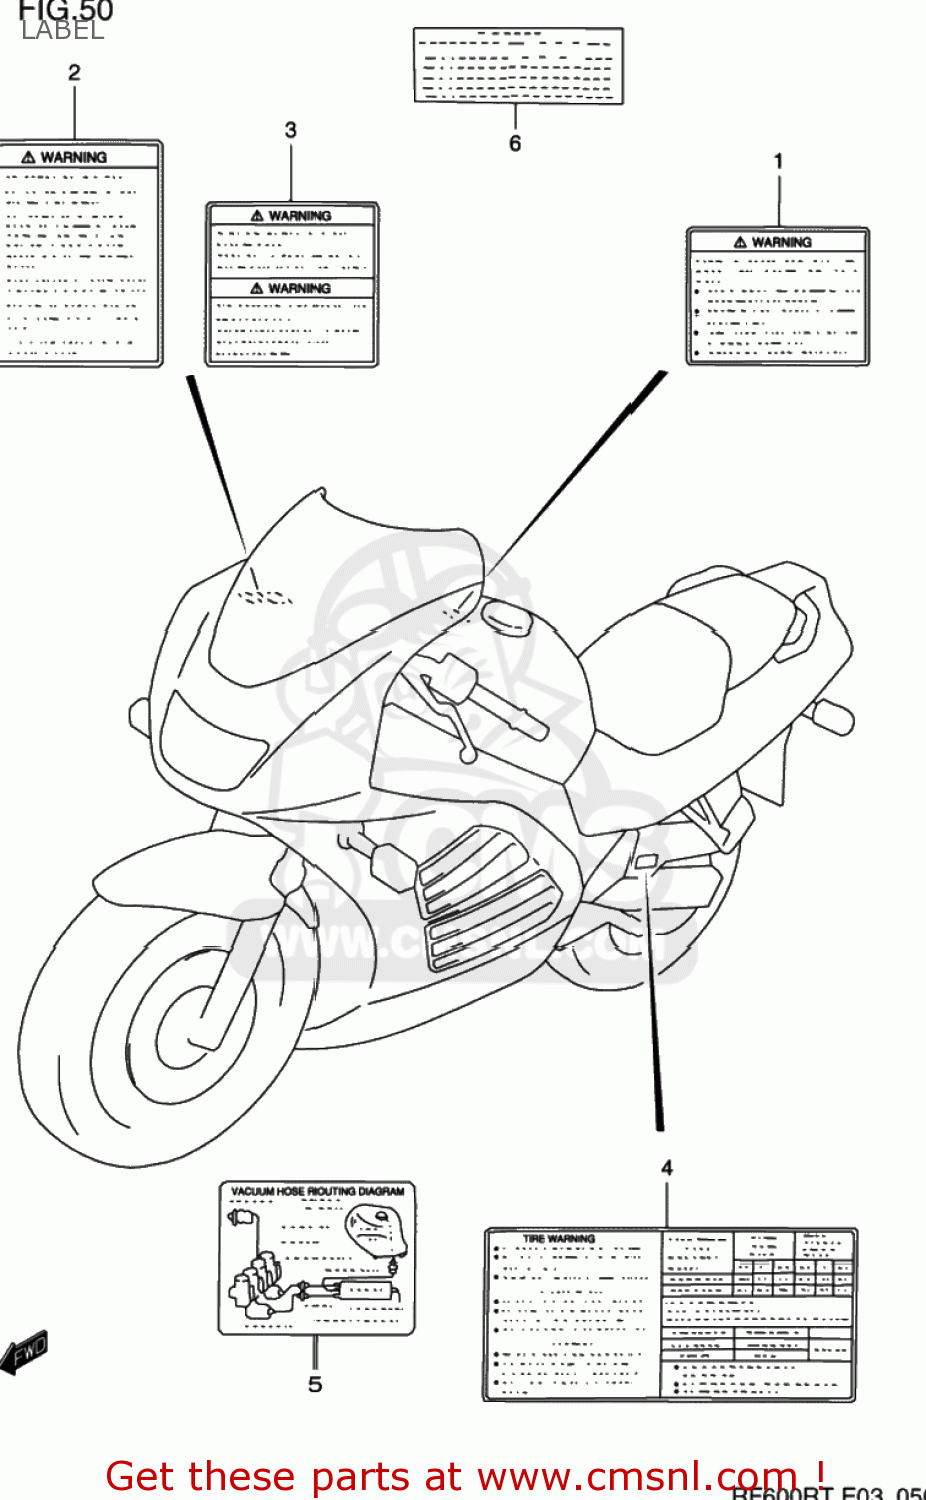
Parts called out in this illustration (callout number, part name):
1	LABEL
2	LABEL (WARNING SCREEN)
3	LABEL (WARNING)
4	LABEL (TIRE INFORMATION)
5	LABEL (VACUUM HOSE ROUTING)
6	LABEL (MANUAL NOTICE)
7	MNL,OWNERS RF90
